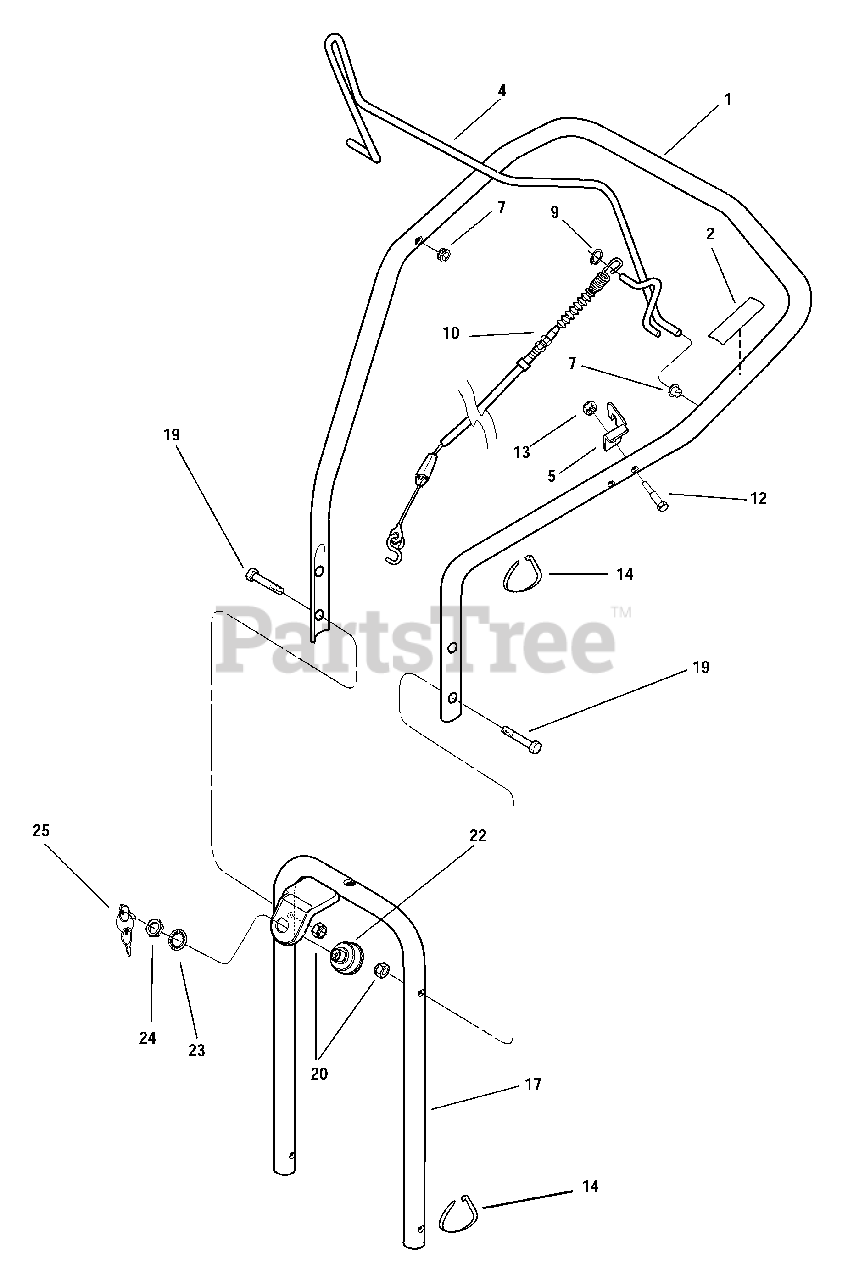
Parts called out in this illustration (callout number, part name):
1	Upper Handlebar w/decal
2	Bail Decal
5	Cable Bracket
7	Nyliner Bushing
9	Retaining Ring, external .312 I.D
10	Control Cable
12	Hex Hd Screw, 1/4-20 x 1-1/8
13	Top Lock Nut, 1/4-20
14	Cable Tie
17	Lower Handlebar
19	Hex Hd Screw, 5/16-18 x 1-1/2, Gr. 5
20	Lock Nut, 5/16-18
22	Ignition Switch
23	Lockwasher, 5/8
24	Hex Nut, 5/8-32
25	Ignition Key
